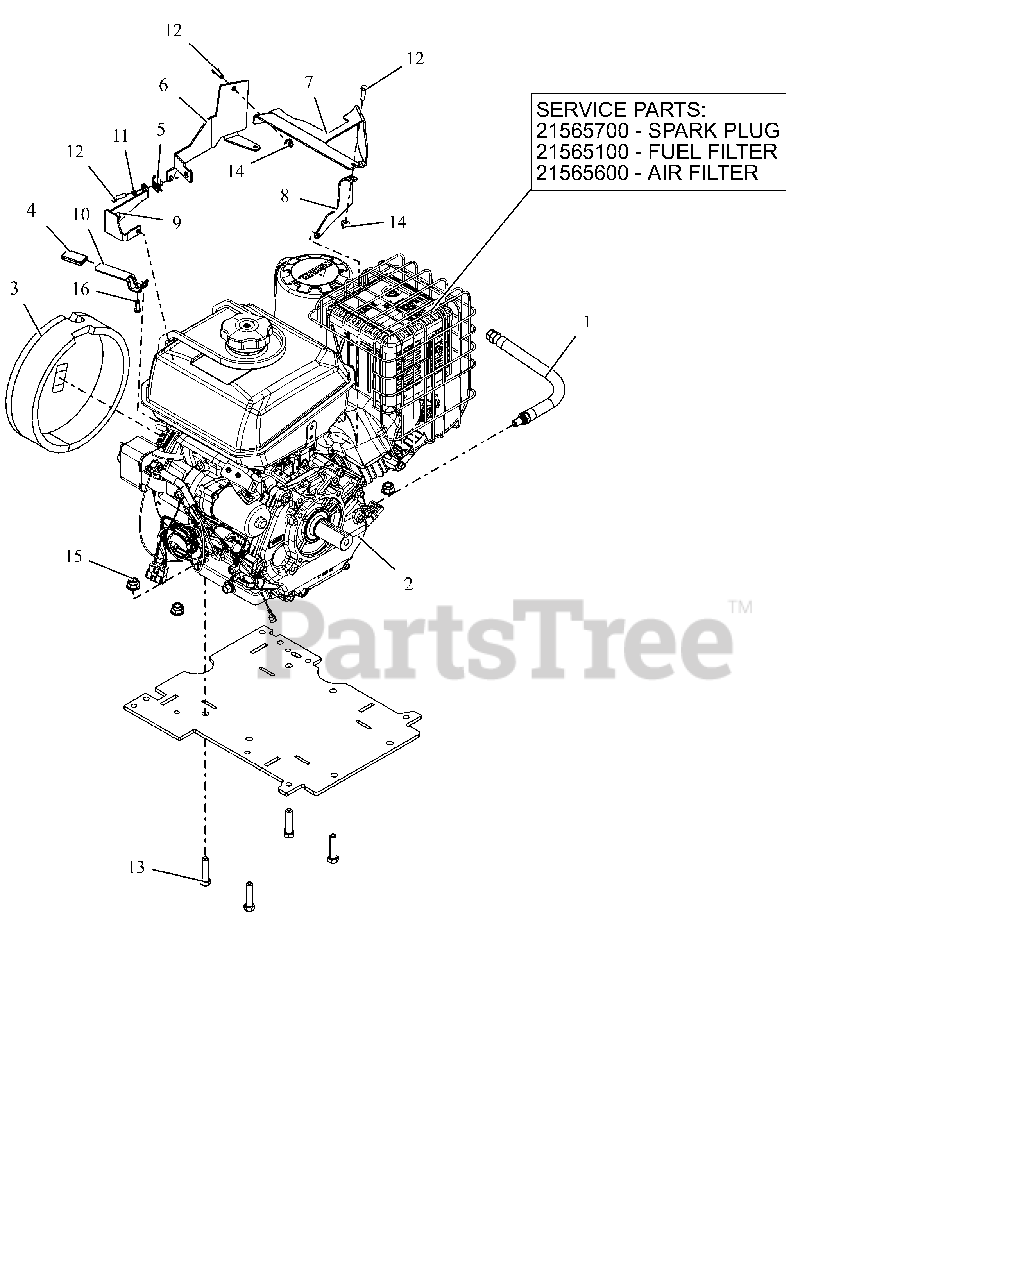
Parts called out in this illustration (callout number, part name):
1	HOSE, OIL DRAIN
2	ENGINE, KOHLER - CH440 12V
2	PLUG,SPARK - KOHLER CH395/440
2	FILTER, FUEL (IN TANK)
2	FILTER,AIR - KOHLER CH395/440
3	COVER, FOAM, KOHLER
4	GRIP, THUMB LATCH
5	NUT-RTNR M6X1
6	PLT, ENGINE SHIELD - FRONT (BLACK)
7	PLT, ENGINE SHIELD LH (BLACK)
8	PLT, ENGINE SHIELD-SUPPORT (BLACK)
9	GUARD, ENGINE WINTER (BLACK)
10	THROTTLE EXT, KOHLER
11	WSHR,LK-REG .250X.062 ZCC
12	BLT, HEX M6-1.0 X 20 G8.8 ZCC
13	BLT,HEX M10-1.5X45 G8.8 ZCC
14	NUT,NYL-FLG M6-1.0 G8.8 ZCC
15	NUT,NYL-FLG M10-1.5 G8.8 ZCC
16	SCR-TAP 10-24X.75 HWH TR YWZC
